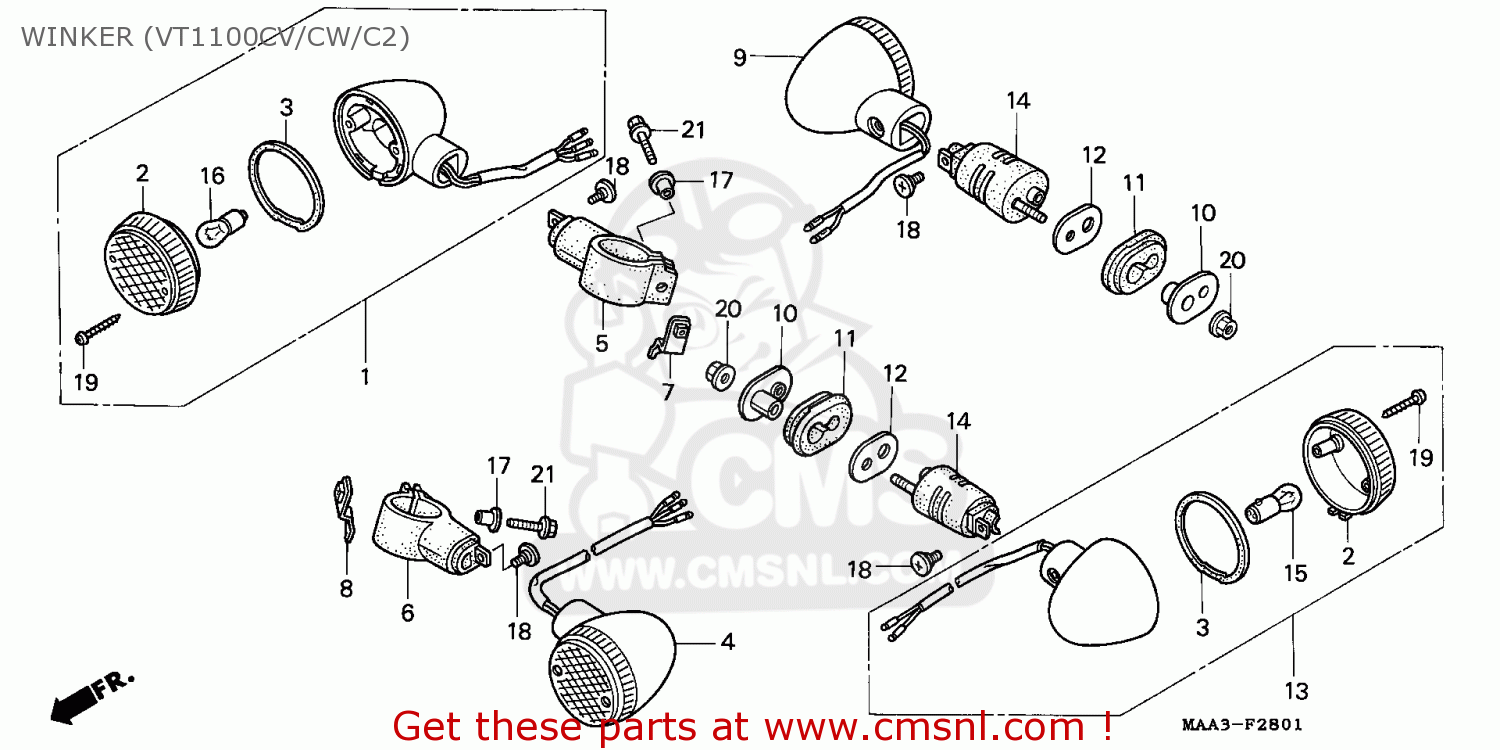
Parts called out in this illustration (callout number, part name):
1	WINKER ASSY,R FR
2	LENS FR.WINKER
3	LENS,PACKING WINK
4	WINKER ASSY,L FR
5	STAY,R.FR.WINKER
6	STAY,L.FR.WINKER
7	STOPPER R,FR WINK
8	STOPPER L,FR WINK
9	WINKER ASSY,R RR
10	WASHER,WINKER MOU
11	RUBBER,RR.WINKER
12	WASHER,RR WINKER
13	WINKER ASSY,L RR
14	STAY COMP,RR WINK
15	BULB, WINKER
16	BULB,WINKER
17	COLLAR,NUMBER PLA
18	SCREW,SPECIAL 6X8
19	SCREW,TAP 4X25
21	BOLT,FLANGE,6X28
